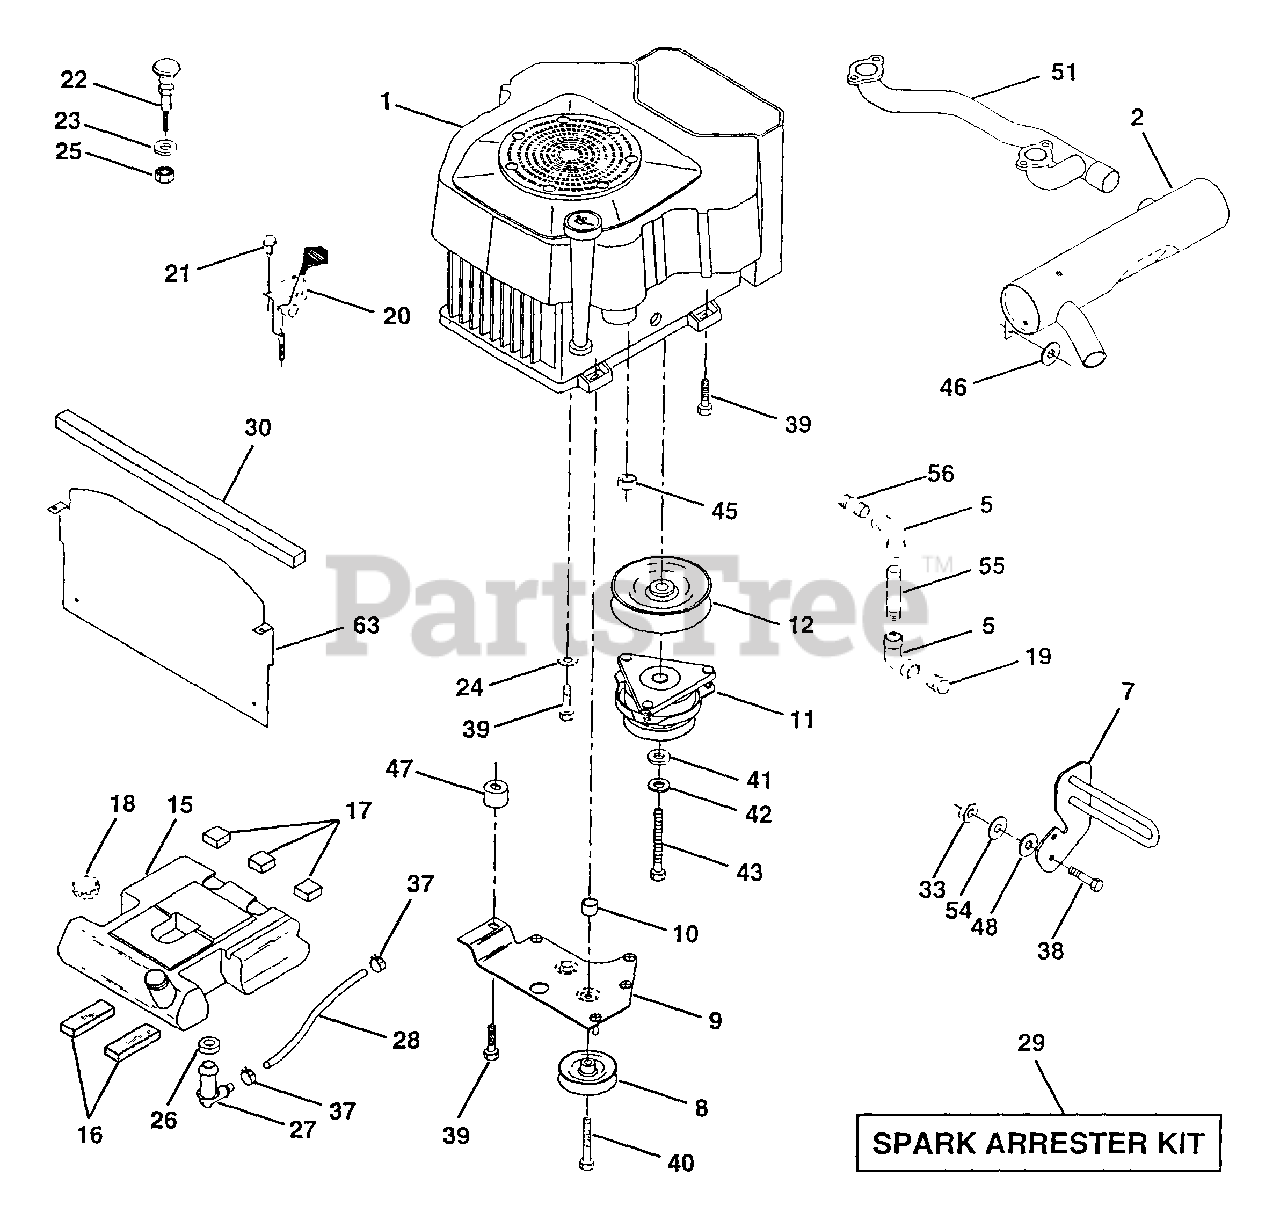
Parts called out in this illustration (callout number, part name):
1	Engine Kohler,
2	Muffler VGT Cylinder
5	Elbow STD 90 Degree 3/8 - 18 NPT
7	Muffler Assembly Guard
8	Pulley V-Idler (AYP part number)
9	Keeper Asm Belt Engine VGT96 (AYP part number)
10	Bushing
11	Clutch Electric (AYP part number)
12	Pulley Engine VGT Elect Clutch
15	Tank Fuel Rear 3.50
16	Pad Spacer
17	Pad Spacer
18	Cap Asm Fuel W/Sym Vented
19	Plug Oil Drain
20	Control Throttle (AYP part number)
21	Screw Hex Thd Cut 1/4 - 20 X 5/8
22	Control Choke
23	Washer 13/32 X 13/16 x 16 Ga
24	Washer Ext Tooth 3/8
25	Nut Keps 3/8-24 UNF
26	Bushing
27	Stem Tank Fuel
28	Fuel Line (AYP part number)
29	Spark Arrester Kit
30	Strip Foam 18"
33	Nut, Hex W/Ins. 3/8-16 UNC
37	Clamp Hose
38	Bolt, Fin Hex 3/8-16 UNC x 1-1/2
39	Screw TT 3/8-16 x 2-1/4 UNC
40	Screw TT 3/8-16 x 4 UNC
41	Washer 1-1/2 OD X 15/32 ID X .250
42	Washer Lock 7/16
43	Bolt Hex 7/16-20 X 4-1/4 Ga 5
45	Nut Flange 1/4-20 Starter Nut
46	Washer 13/32 x 1 x 16 Ga.
47	Spacer Engine CV22 Round PM
48	Washer 13/32 x 1-1/4 x 7 Ga.
51	Pipe Crossover CV22 (AYP part number)
54	Washer Flat 13/32 x 7/8 x 14 Ga.
55	Nipple, Pipe 3/8 NPT x 4-1/2
56	Nipple, Pipe 3/8 NPT x 1.00
63	Shield, Heat VGT 22 HP YP/Husq.
